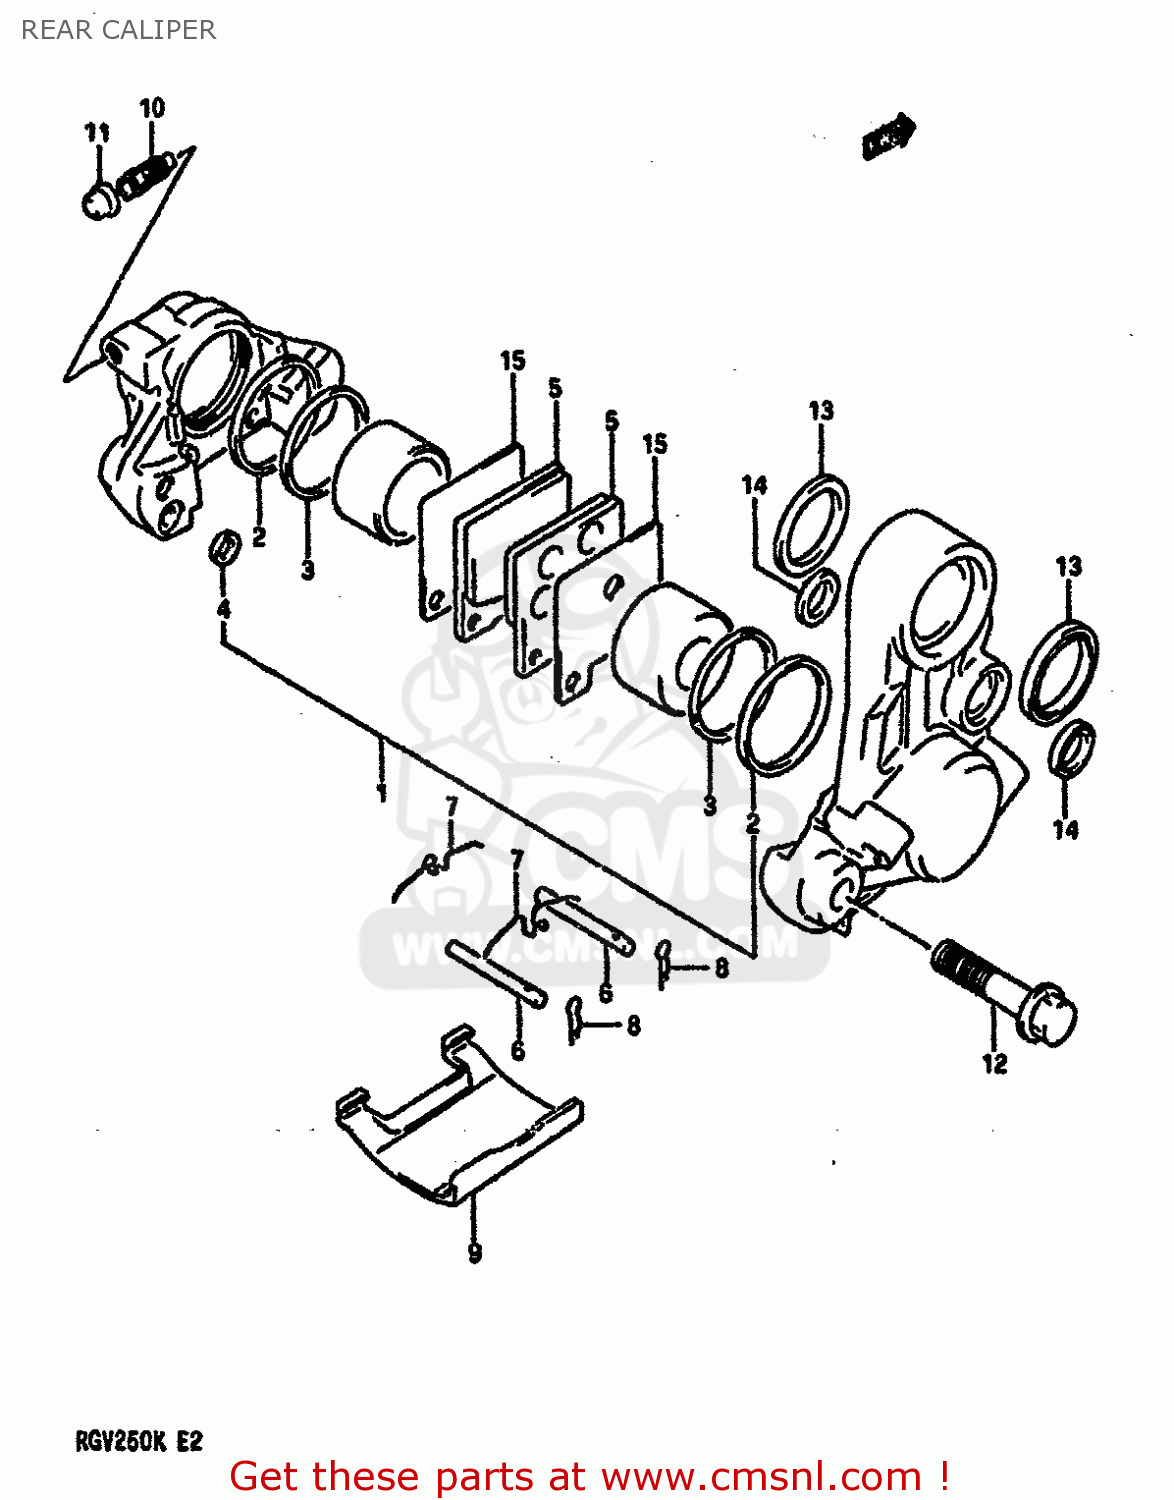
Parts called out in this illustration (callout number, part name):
1	PISTON SET
2	SEAL,PISTON
3	SEAL,WIPER
4	SEAL,JOINT
5	PAD,BRAKE
6	PIN,PAD
7	SPRING
8	CLIP,PAD PIN
9	COVER
10	BLEEDER
11	CAP,BREATHER
12	BOLT,HOUSING
13	SEAL,OIL(28X35X5)
14	SEAL,RR CUSHION ROD LWR
15	SHIM,PAD
